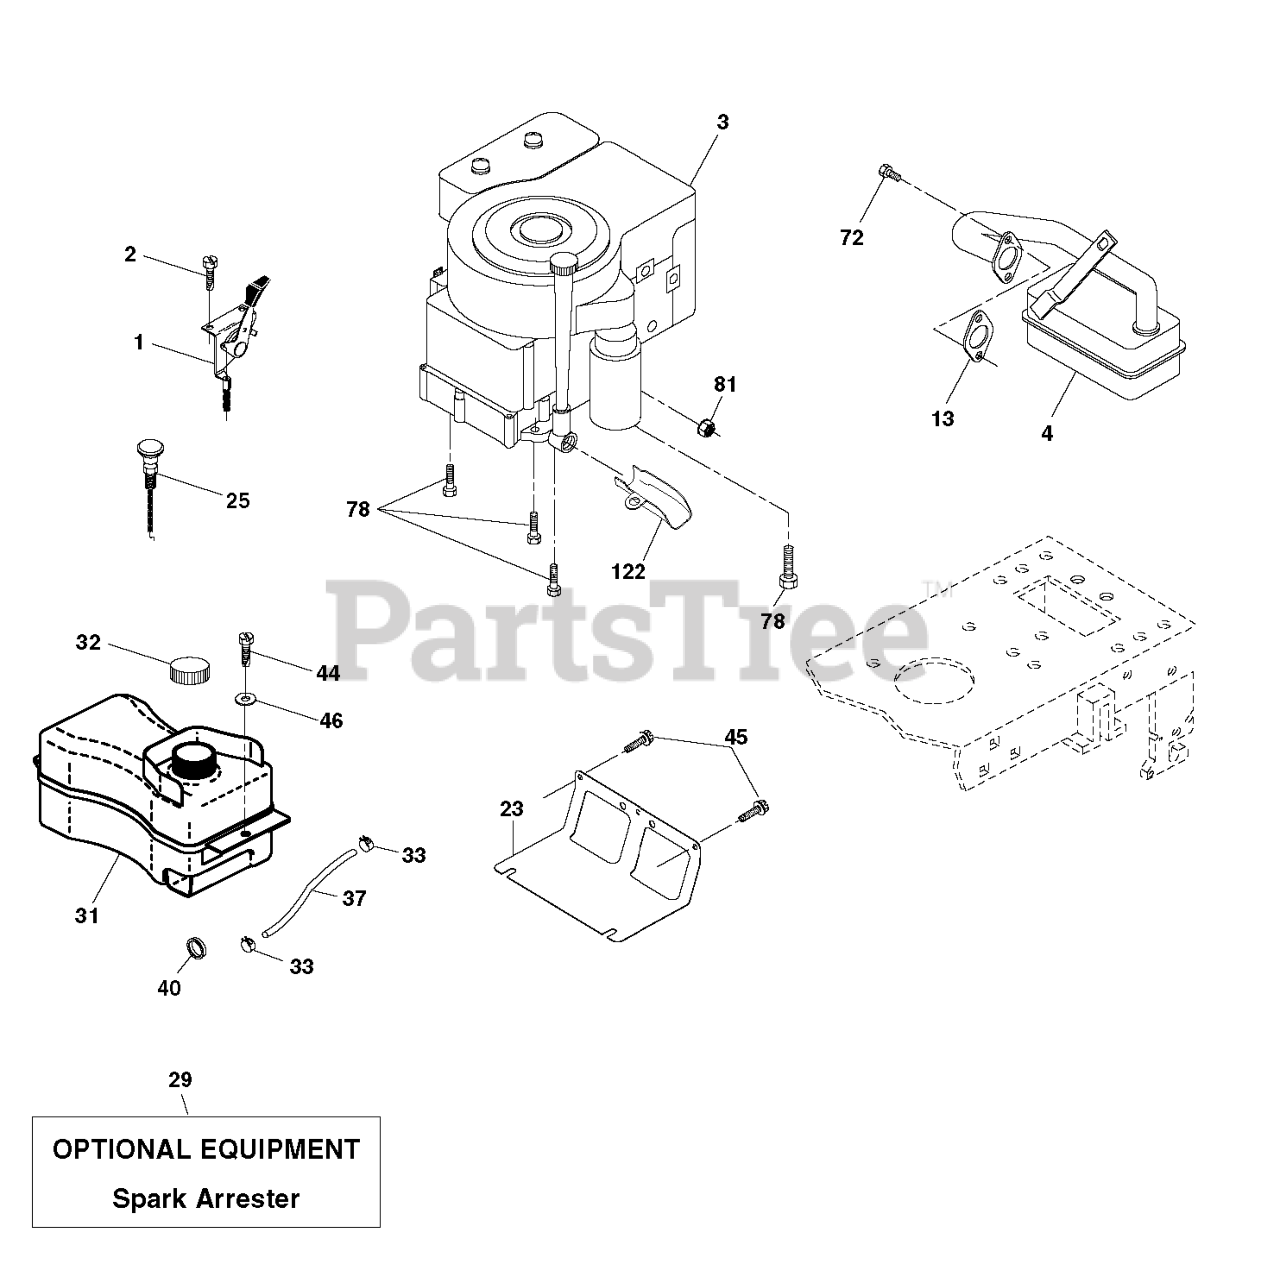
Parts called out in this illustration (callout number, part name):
1	CONTROL.THROTTLE/CHOKE.BLACK
2	SCREW
4	MUFFLER.B&S.MODEL.21.11HP.OHV
13	REPL BY 532 27 22-93
23	SHIELD.BROWNING.DBR.GUARD
25	KNOB.ERGO.EXTENDED.RED (1 2)
29	KIT.SPARK ARRESTOR 794945 B&S
32	CAP ASM.FUEL.2.25"FR.
33	HOSE CLAMP
37	LINE.FUEL.20
40	BUSHING.SNAP.NYL.BLK.
44	SCREW HEXWSHR 1/4-20X3/4
45	SCREW, 3/8-16X3/4
72	SCREW.SOCKET HD.5/16-1
78	SCREW.3/8-16
81	NUT
122	EXTENSION DRAIN OIL
